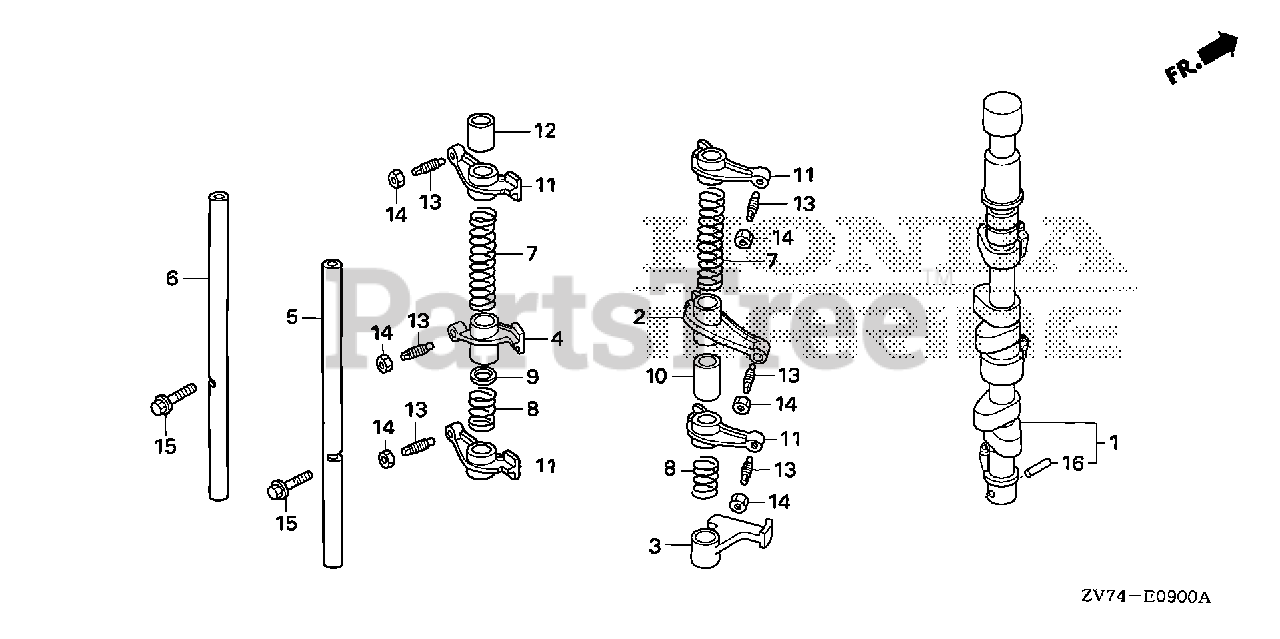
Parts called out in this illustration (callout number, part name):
2	ARM, IN. VALVE ROCKER
3	ARM, FUEL PUMP ROCKER
4	ARM, EX. VALVE ROCKER
5	SHAFT, IN. ROCKER ARM
6	SHAFT, EX. ROCKER ARM
7	SPRING, ROCKER ARM (C)
8	SPRING, ROCKER ARM B
9	COLLAR, ROCKER ARM A
10	COLLAR, ROCKER ARM B
11	ARM, VALVE ROCKER
12	COLLAR, ROCKER
13	SCREW, TAPPET ADJUSTING
14	NUT, TAPPET ADJUSTING
15	BOLT, FLANGE (6X28)
16	ROLLER (3X16.8)
